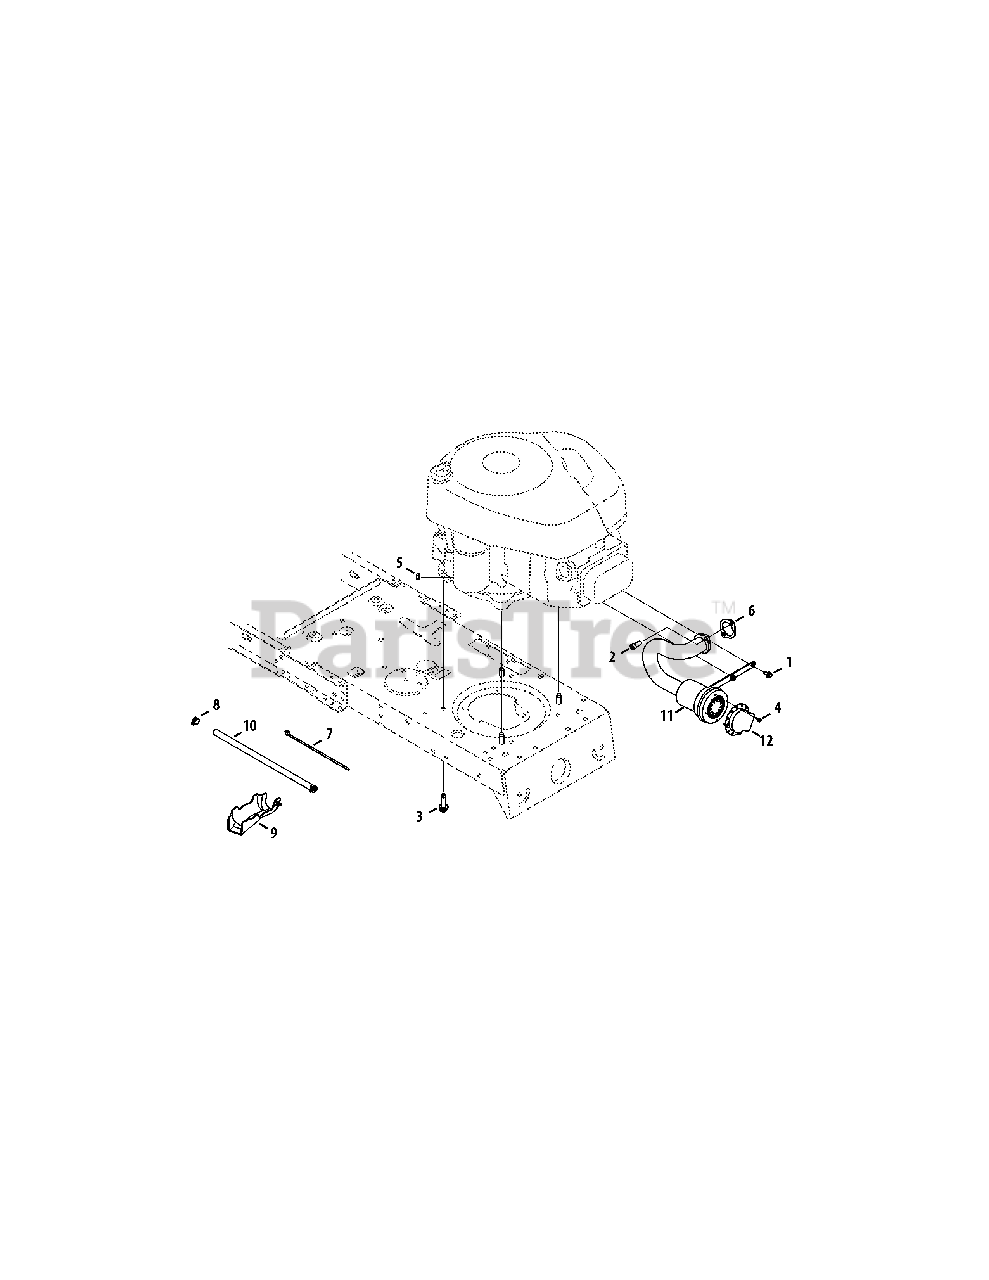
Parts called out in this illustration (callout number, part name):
1	Screw, ab, #8-18, 0.500
2	Tap Screw, 3/8-16, 1.000
3	Tap Screw, 1/4-20, 0.500
4	Screw, Socket Head, 5/16-18, .750
5	Sems Nut, 1/4-20
6	Exhaust Gasket, 10 HP B&S #272293
7	Cable Tie, 3/16 X .05 X 7.4
8	Hose Clamp, .490 Dia.
9	Oil Drain Sleeve
10	Hose, fuel, low Permeation, 1/4
11	Muffler
12	Muffler Deflector
